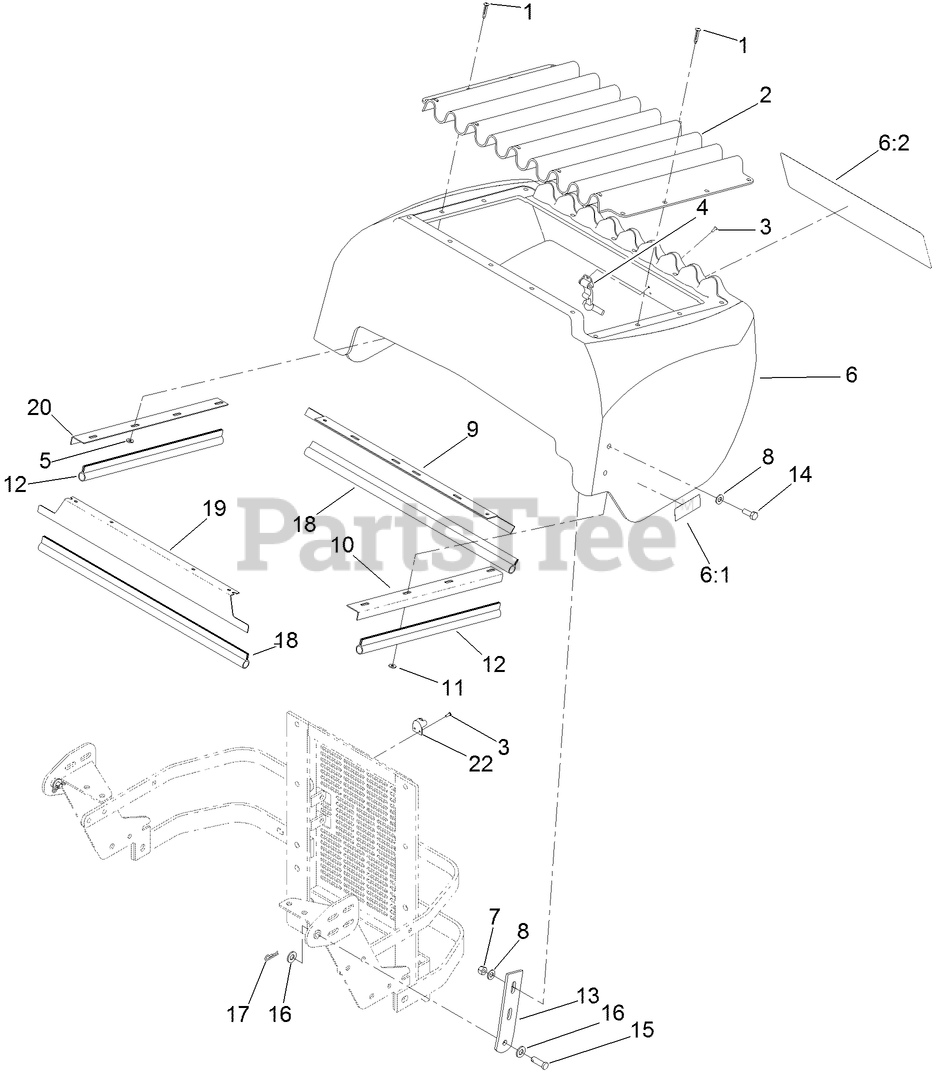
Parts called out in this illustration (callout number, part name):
2	SCREEN-RADIATOR
3	RIVET
4	LATCH-RUBBER
5	WASHER-SPRING
6	HOOD ASM
6:1	DECAL-LOW SULFUR
6:2	DECAL-CONSOLE
7	NUT-LOCK, NI
8	WASHER-PLAIN
9	ANGLE-RADIATOR, BOTTOM
10	ANGLE-RADIATOR, LH
11	WASHER-FLAT
12	SEAL-TRIM
13	PLATE-HINGE, HOOD
14	SCREW-HH
15	PIN-CLEVIS
16	WASHER-FLAT
17	PIN-COTTER
18	SEAL-TRIM
19	BRACKET SEAL, RADIATOR FRONT
20	ANGLE-RADIATOR, RH
22	KEEPER
